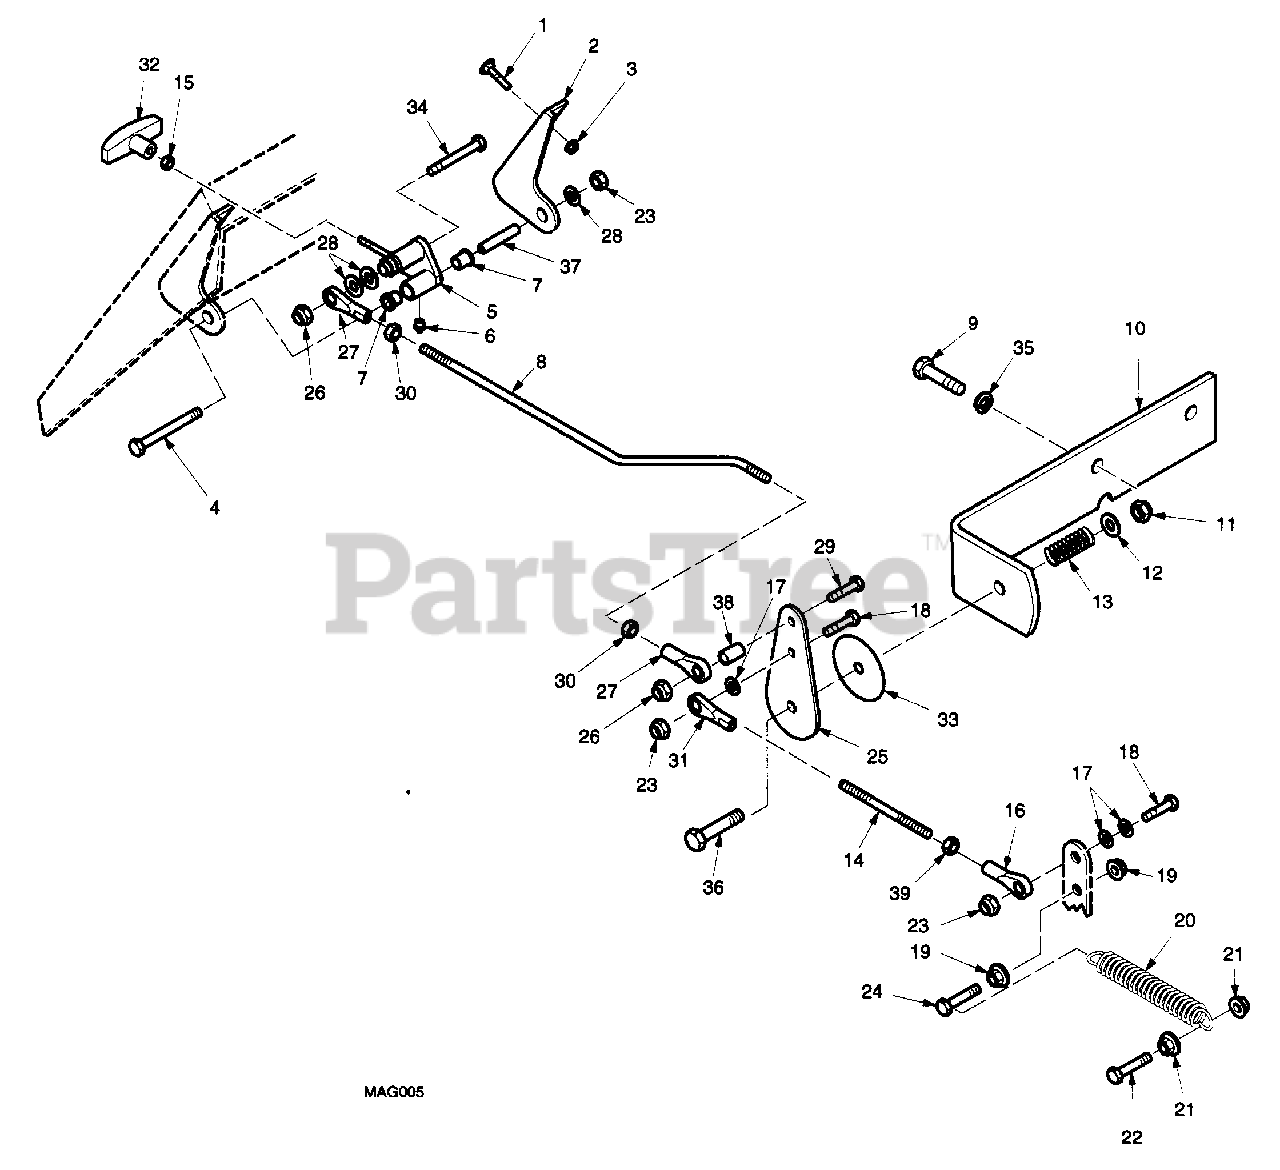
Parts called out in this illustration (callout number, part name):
1	CARRIAGE BOLT, 1/4-20 X .75
2	MOUNTING BASE, THROTTLE
3	SERR. FL. HEX NUT, 1/4-20
4	BOLT, HEX HEAD, 5/16-18 X 2-3/4
5	LEVER, THROTTLE(INCLUDES 6, 7)
6	GREASE FITTING
7	BUSHING, OILITE - .50 I.D.
8	ROD, THROTTLE CONTROL
9	BOLT, HEX HEAD, M10 - 1.25 X 30
10	MOUNTING BRACKET, THROTTLE
11	HEX LOCKNUT, ELASTIC STOP, 5/8-11
12	FLATWASHER, 5/8
13	SPRING, FRICTION CONTROL
14	STUD, 5/16-24 X 4.50
15	HEX NUT, 5/16-18
16	ROD END, 5/16-24 RH THREAD
17	FLATWASHER, 5/16(.344 X .688 X .065)
18	BOLT, HEX HEAD, 5/16-18 X 1-1/4
19	SERR. FL. HEX NUT, 1/4-20
20	SPRING, THROTTLE CONTROL
21	SERR. FL. HEX NUT, 5/16-18
22	BOLT, HEX HEAD, 5/16-18 X 2-1/4
23	HEX LOCKNUT, ELASTIC STOP, 5/16-18
24	BOLT, HEX HEAD, 1/4-20 X 1-14
25	LEVER, THROTTLE
26	HEX LOCKNUT, ELASTIC STOP, 3/8-16
27	BALL JOINT, 3/8-24 RH THREAD
28	FLATWASHER, 5/16
29	BOLT, HEX HEAD, 3/8-16 X 1-1/2
30	HEX NUT, 3/8-24
31	ROD END, 5/16-24 LH THREAD
32	KNOB, SHIFTER
33	DISC, FRICTION
34	BOLT, HEX HEAD, 3/8-16 X 3-3/4
35	LOCKWASHER, 7/16
36	BOLT, HEX HEAD, 5/8-11 X 3-1/2
37	SLEEVE
38	SLEEVE
39	HEX NUT, 5/16-24
